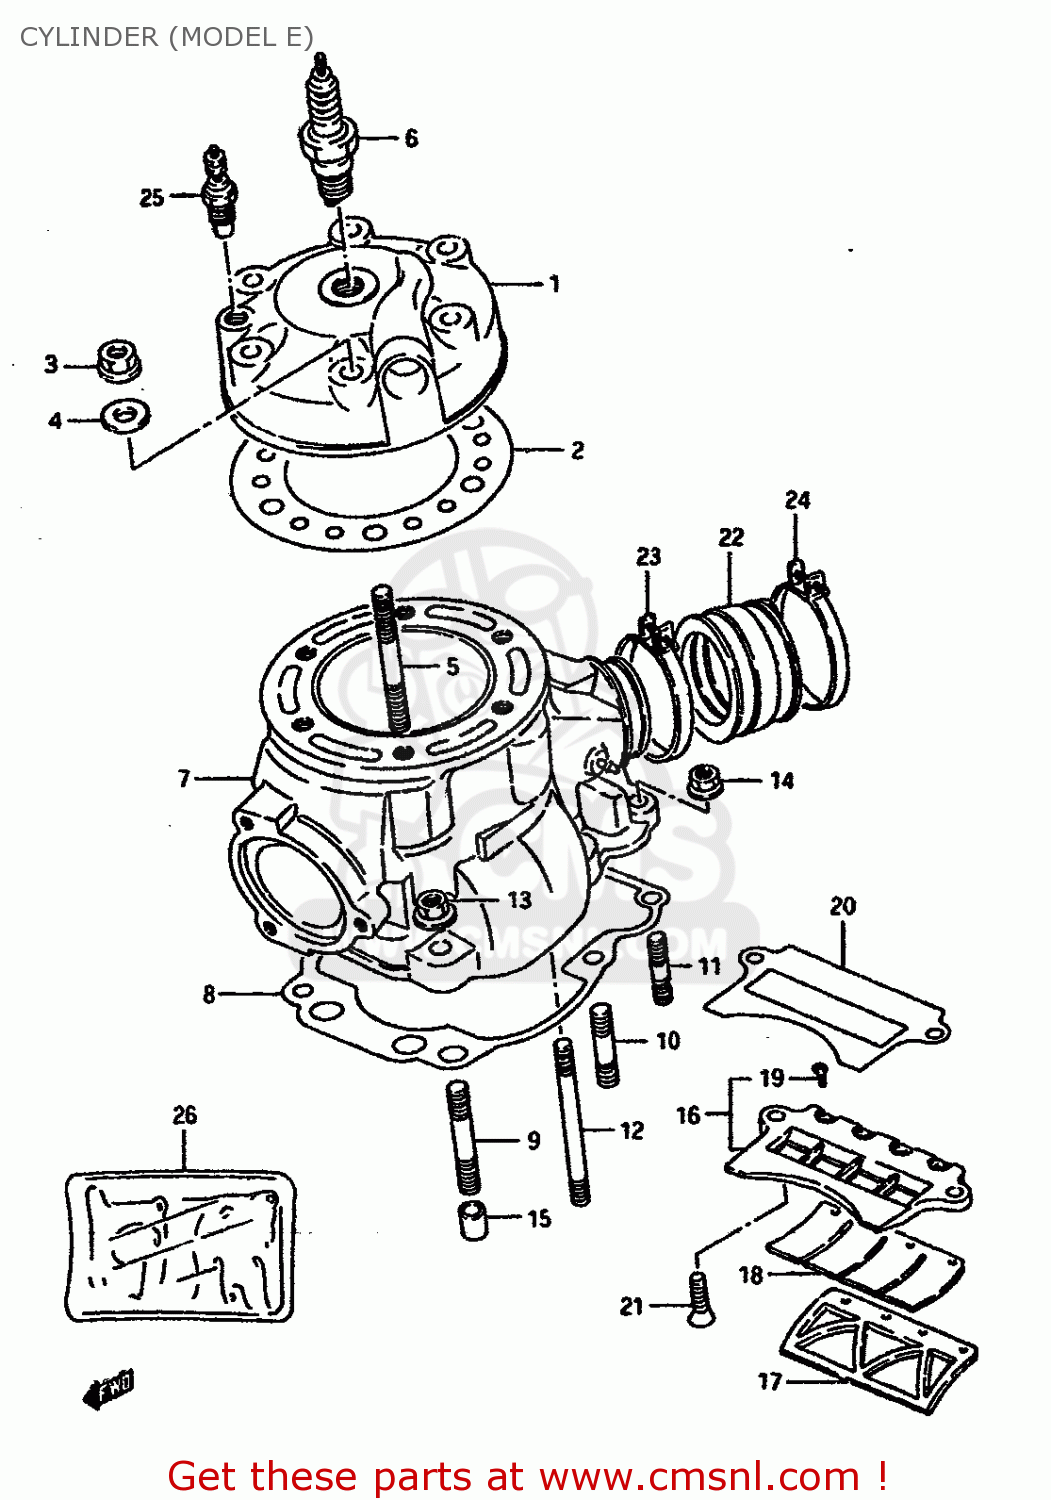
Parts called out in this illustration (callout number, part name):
1	HEAD,CYLINDER
2	GASKET,CYLINDER HEAD (NAS)
3	NUT 8MM
4	WASHER (8.5X19X2.3)
5	STUD
6	PLUG,SPARK(NGK B-8EN)
7	CYLINDER
8	GASKET,CYLINDER
9	STUD
10	STUD BOLT (8X25)
11	STUD BOLT L:20
12	STUD BOLT
13	NUT 8MM
14	NUT 6MM
15	PIN
16	VALVE ASSY,REED
17	STOPPER,REED VALVE
18	VALVE,REED
19	SCREW,REED VALVE
20	GASKET,REED VALVE (MCA)
21	SCREW
22	PIPE,INTAKE
23	CLAMP
24	CLAMP
25	GAUGE ASSY,WATER TEMPERATURE
26	GASKET SET
